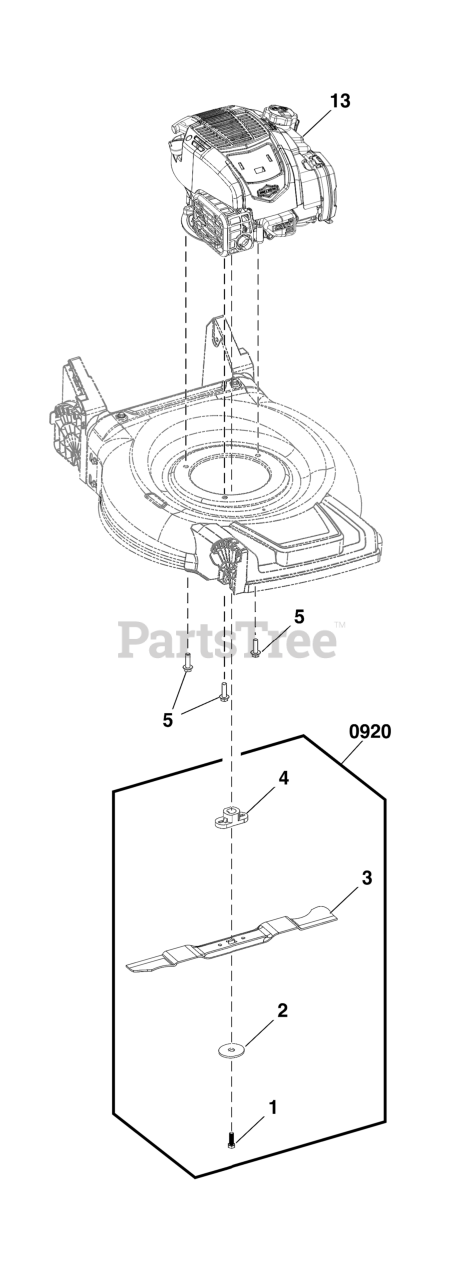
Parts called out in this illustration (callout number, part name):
1	BOLT, Blade
2	WASHER
3	BLADE, Mower
4	ADAPTER, Blade
5	BOLT
13	ENGINE
0920	KIT, Blade
